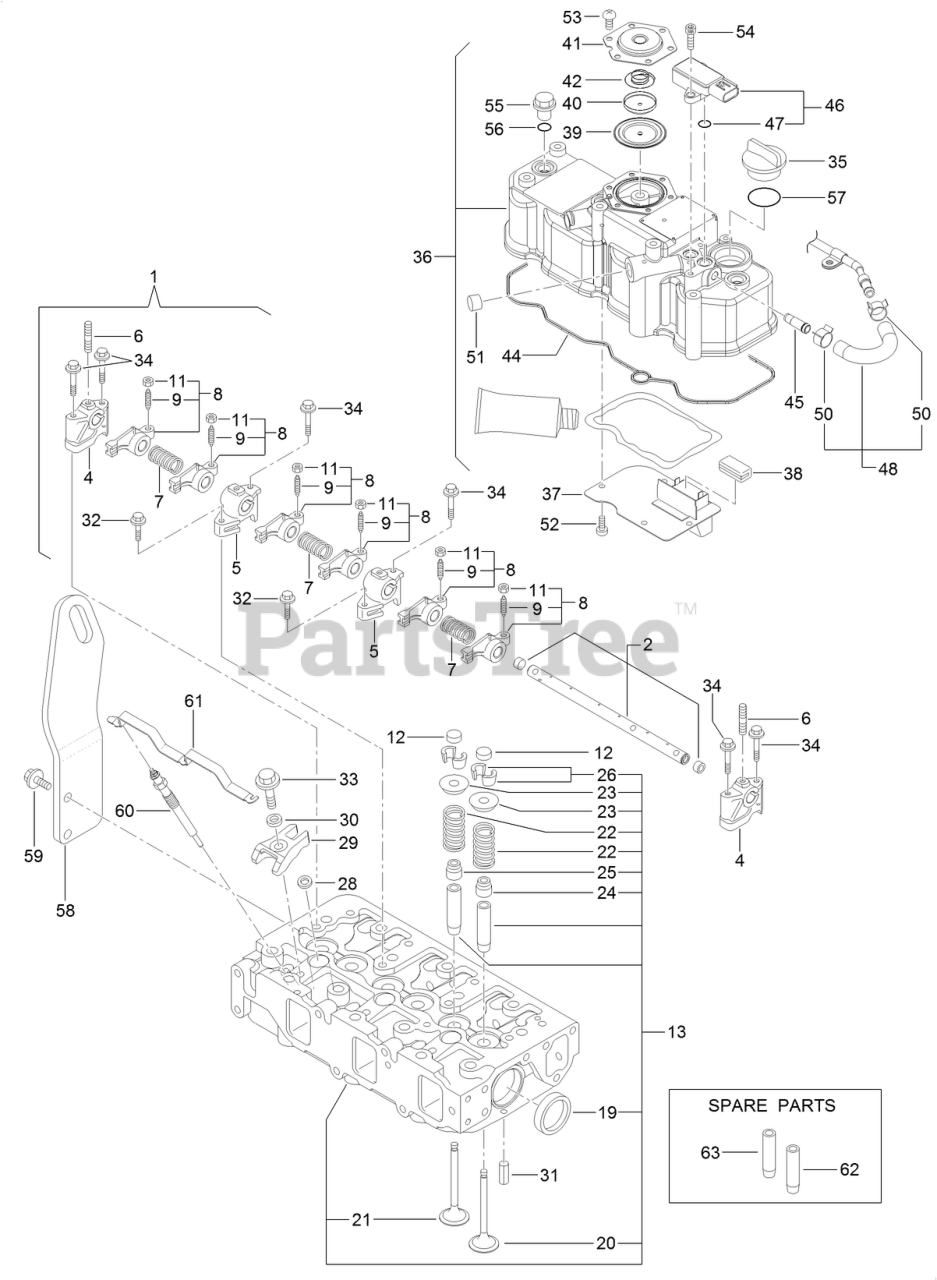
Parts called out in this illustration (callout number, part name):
1	SHAFT ASM
4	SUPPORT
5	SUPPORT
7	SPRING
8	ARM-ROCKER
9	SCREW-ADJUST, VALVE
12	CAP-VALVE
13	CYLINDER HEAD ASM
22	SPRING
23	RETAINER-SPRING
24	SEAL-STEM, VALVE
25	SEAL-STEM, VALVE
26	PIN-COTTER
28	GASKET-INJECTOR
29	RETAINER-INJECTOR
30	WASHER-INJECTOR
31	PIN-SPRING
35	COVER-FILLER
36	CYLINDER HEAD COVER ASM
38	BAFFLE
39	DIAPHRAGM
41	PLATE-BREATHER
42	SPRING-DIAPHRAGM
44	GASKET-HEAD, CYLINDER
46	SENSOR-PRESSURE
47	O RING-SENSOR, PRESSURE
48	HOSE ASM
50	CLIP-HOSE
56	O-RING
57	O-RING
58	LIFTER, ENGINE
59	BOLT, M8 X 20 PLATED
60	PLUG-GLOW
61	CONNECTOR-PLUG, GLOW
63	GUIDE-VALVE
